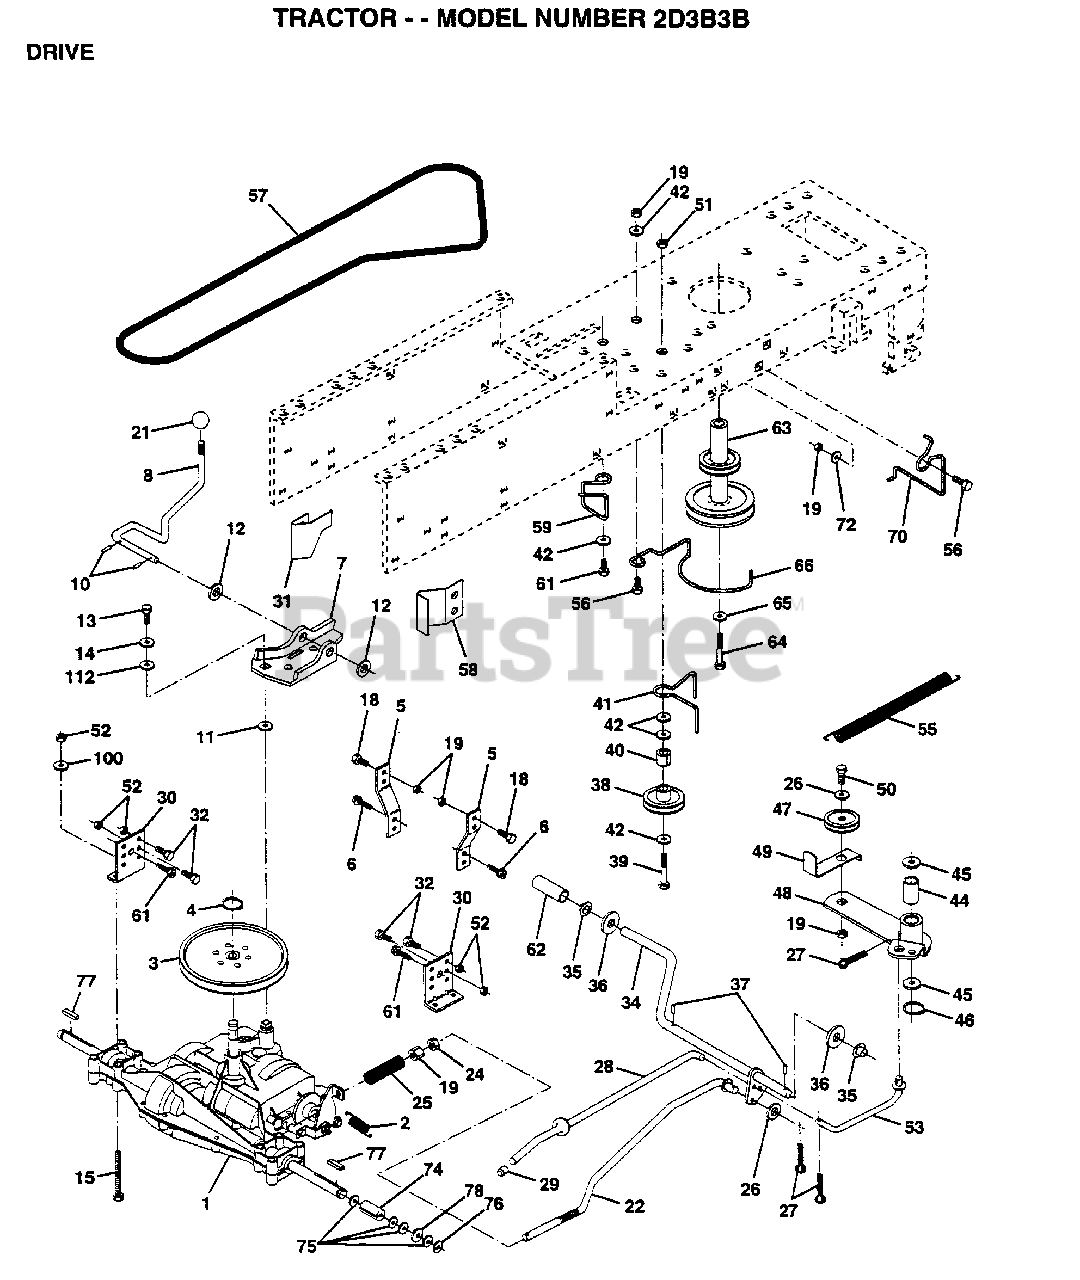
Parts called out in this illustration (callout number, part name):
2	SPRING.BRAKE.RETU
3	PULLEY TRANS
5	STRAP TORQUE
6	SCREW
8	SHIFT ROD
10	PIN COTTER 1/8
11	WASH-SHFT PLT LT
12	WASHER
13	BOLT.1/4-28.W/PAT
14	LOCKWASHER
15	BOLT HEX
18	BOLT
19	NUT
21	KNOB T (1/2-HOLE)
22	BRAKE ROD
24	NUT
25	SPRING ROD LT
26	WASHER
27	COTTER PIN
28	ROD.BRAKE.PARK.LT
29	PLUNGER CAP T
30	TRANSAXLE MTG BKT
31	"KEEPER,BELT LH T"
32	BOLT
35	NYLON BEARING
36	WASHER LT
38	PULLEY.IDLER.FLAT
39	BOLT
40	SPACER T
41	BELT KEEPER LT
42	WASHER
44	"LY, BEARING"
45	WASHER LT
46	KLIP RING
48	ARM IDLER
49	RETAIN BELT
53	"LINK, CLUTCH T"
55	"SPRING, RETURN LT"
58	"KEEPER,BELT RH T"
59	KEEPER BELT CNTSP
61	SCREW
62	PEDAL COVER T
63	PULLEY.ENGINE
64	BOLT
65	LOCKWASHER
66	KEEPER.BELT.ENG.L
70	KEEPER BELT ENG
72	WASHER
74	SPACER LT
75	WASHER
76	E-RING LT
77	SQUARE KEY
78	WASHER
100	WASHER M
112	WASHER LT
